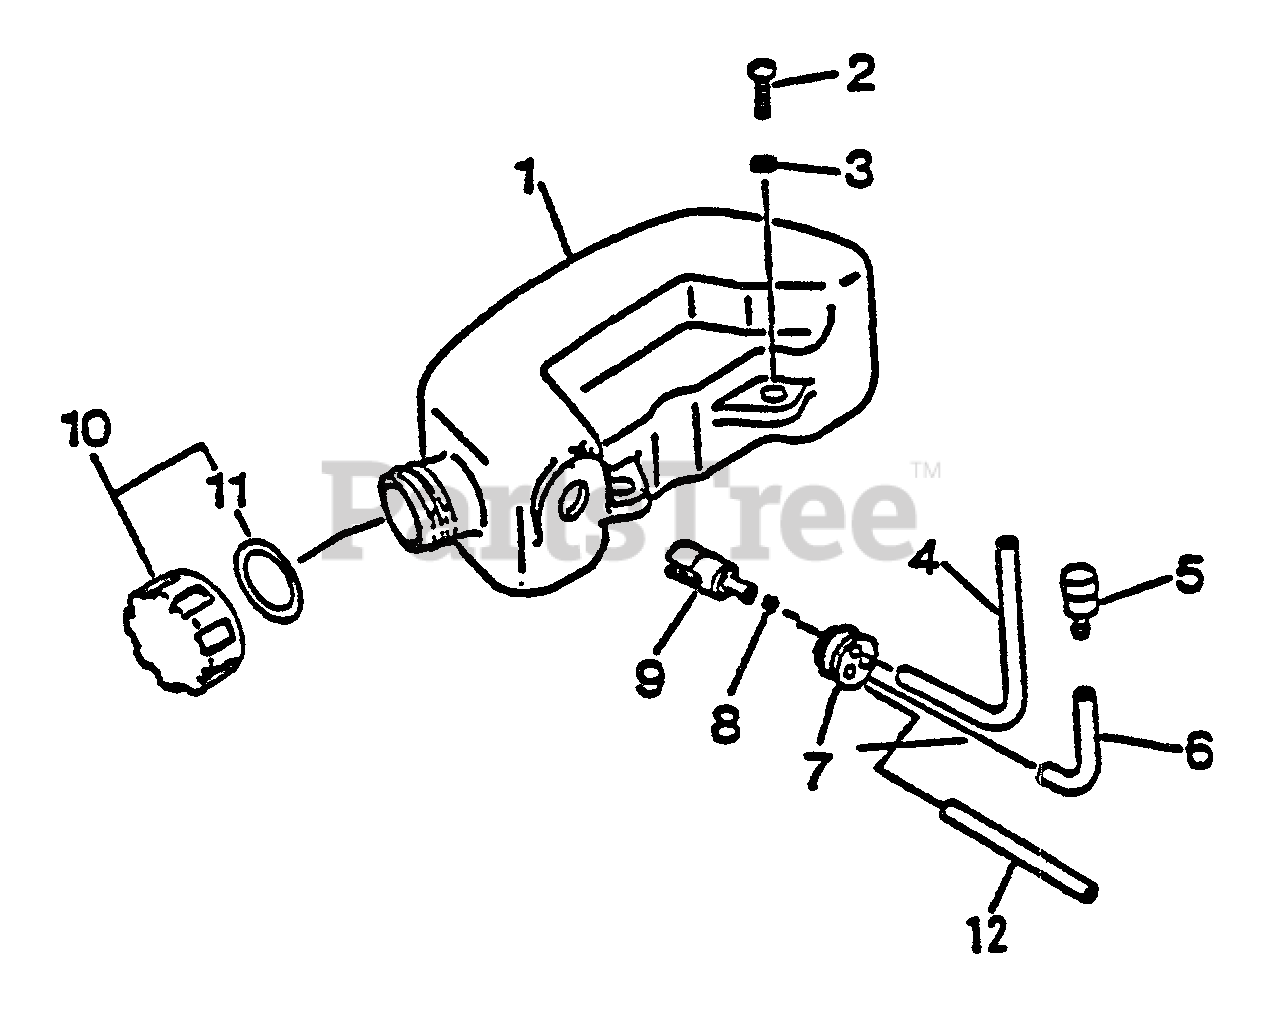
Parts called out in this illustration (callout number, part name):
1	TANK, FUEL
2	SCREW - 5X16
3	WASHER - 5
4	PIPE - 3X5X195 -- BLACK
5	VENT, FUEL TANK
6	PIPE - 3X6X70 -- CLEAR
7	GROMMET
8	CLIP - 6
9	FILTER, FUEL
10	CAP ASSY
11	GASKET, CAP
12	PIPE - 3X6X110 -- CLEAR
